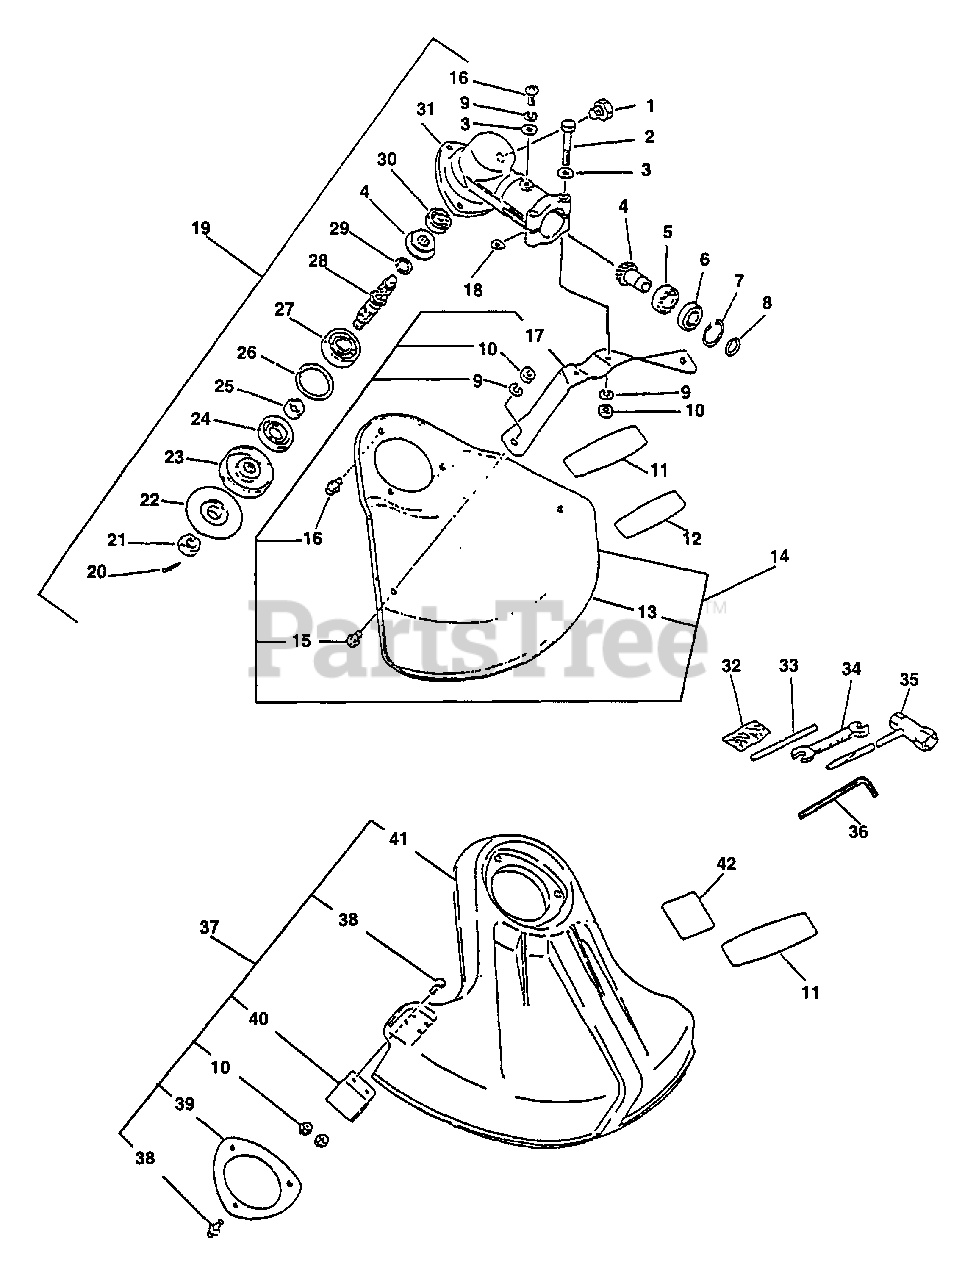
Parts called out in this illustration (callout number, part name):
1	BOLT 8×8 SP
1	BOLT 8×6
2	BOLT 5×35 SP
3	WASHER, FLAT 5.5×10×0.8
4	GEAR SET
5	BEARING, BALL 6900
6	BEARING, BALL 6900Z
7	RING, SNAP Ø22
8	RING, SNAP Ø12
9	WASHER, SPRING 5
10	NUT M5
11	LABEL, ECHO
12	LABEL, DANGER
13	SHIELD, METAL DEBRIS
14	SHIELD ASSY
15	SCREW 5×8
16	SCREW 5×10
17	BRACKET, SHIELD MOUNTING
19	GEAR CASE ASSY
20	PIN, COTTER 2×22
22	PLATE, ADAPTOR - LOWER
23	PLATE, ADAPTER - UPPER
24	SEAL, OIL 22
25	SPACER 11.8×15×9
26	RING, SNAP Ø32
27	BEARING, BALL - 6201 C3
28	SHAFT, GEAR
29	RING, SNAP Ø10
30	BEARING, BALL 609
31	HOUSING, GEAR CASE
32	PIN, COTTER 2×22 (PKG. OF 10)
33	TOOL, LOCKING 5×120 MM
34	SPANNER 8×10
35	T-WRENCH 17x-19 L200
36	WRENCH, ALLEN 3 MM
37	DEBRIS SHIELD ASSY
38	SCREW 5×16
39	PLATE, SHIELD Ø49.5 MM
40	CUTTER, LINE
41	SHIELD, DEBRIS
42	LABEL, CAUTION
